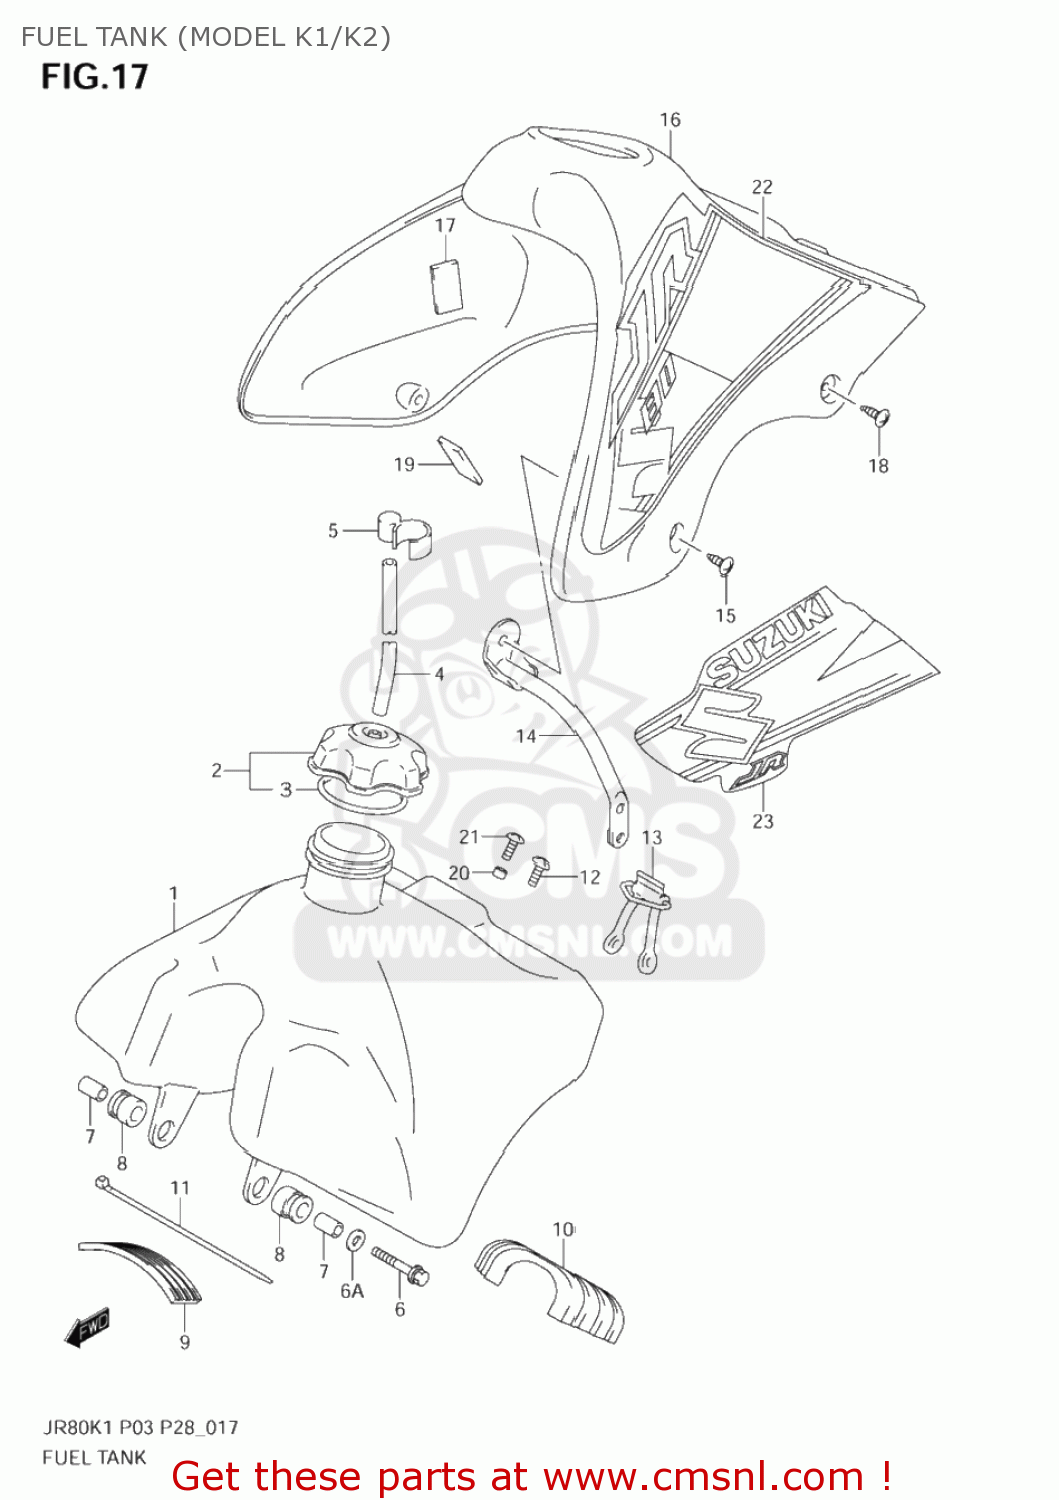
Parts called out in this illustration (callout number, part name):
1	TANK,FUEL
2	CAP SET,FUEL TANK
3	GASKET,CAP (NAS)
4	HOSE(5X8.2X600)
5	CLAMP
6	BOLT, FRONT
6A	WASHER(6.5X18X1)
7	SPACER(6.5X10X16)
8	CUSHION
9	CUSHION,FUEL TANK UPR FR
10	CUSHION,FUEL TANK UPR RR
11	CLAMP(L:250)
12	SCREW
13	BAND,FUEL TANK RR
14	BRACKET,FUEL TANK COVER
15	SCREW(6X16)
16	COVER,FUEL TANK
17	CUSHION,FR FENDER
18	SCREW
19	CUSHION
20	SPACER(6.1X8X5.2)
21	BOLT
22	TAPE SET,FUEL TANK COVER
23	TAPE SET,FUEL TANK COVER
